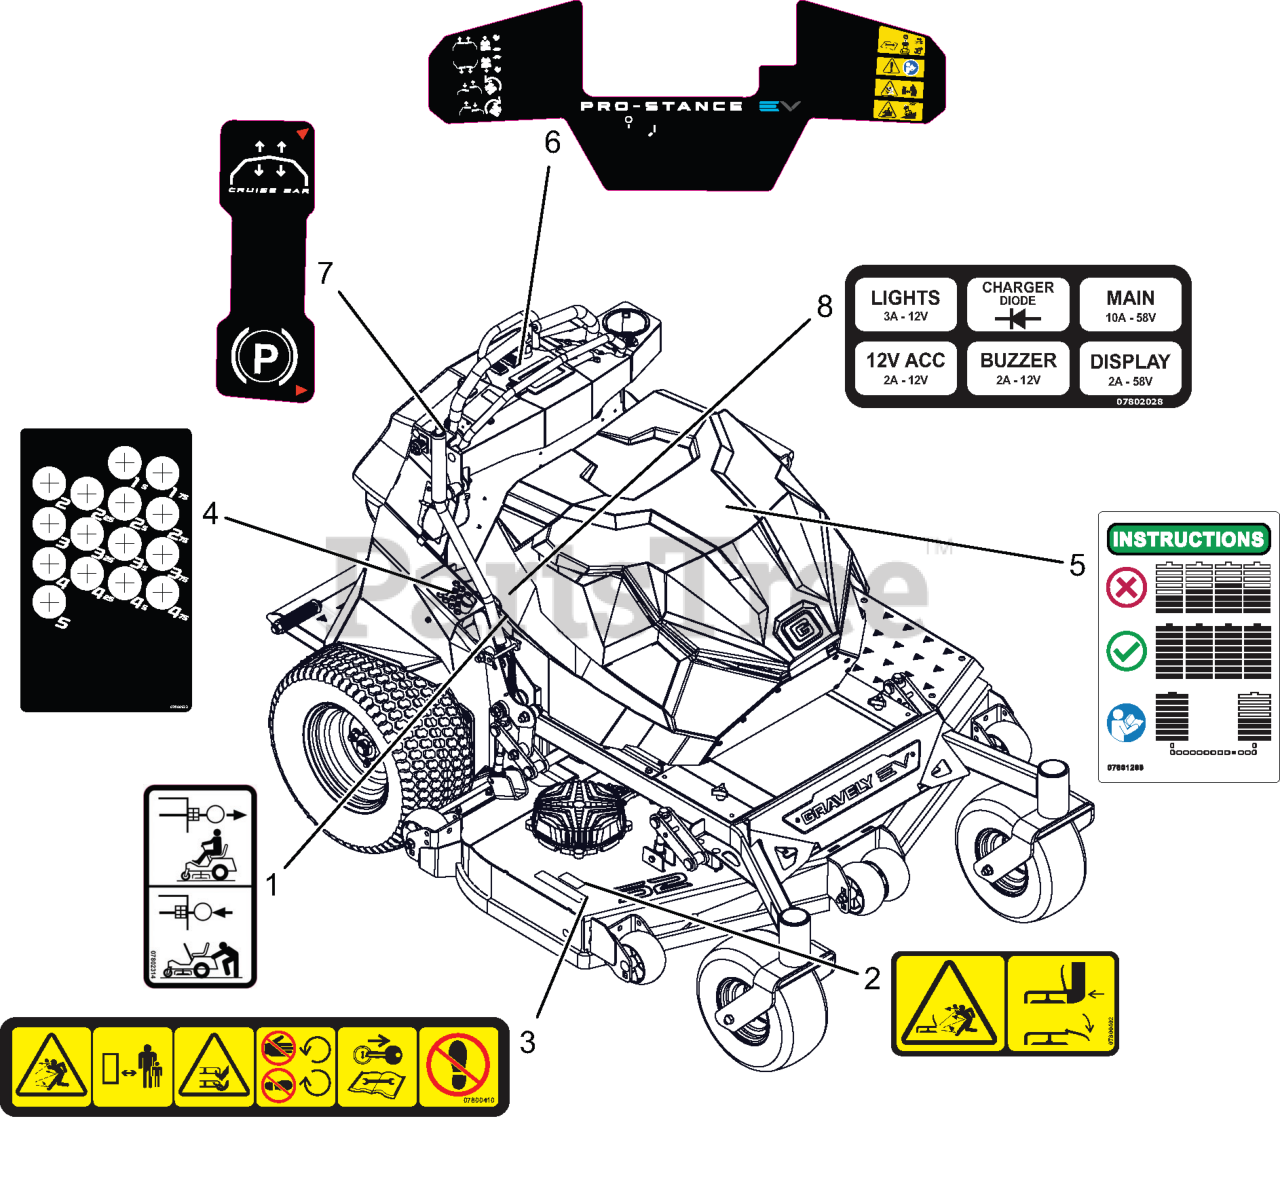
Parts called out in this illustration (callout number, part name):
1	DECAL, TRANSMISSION DISCONNECT
2	DECAL, SAFETY - DECK GUARDING
3	DECAL, DECK SAFETY
4	DECAL, DECK - HEIGHT ADJUST
5	DECAL, BATTERY BALANCE
6	DECAL- DASH PSEV MAIN
7	DECAL- DASH PSEV SECONDARY
8	DECAL, FUSE LAYOUT
